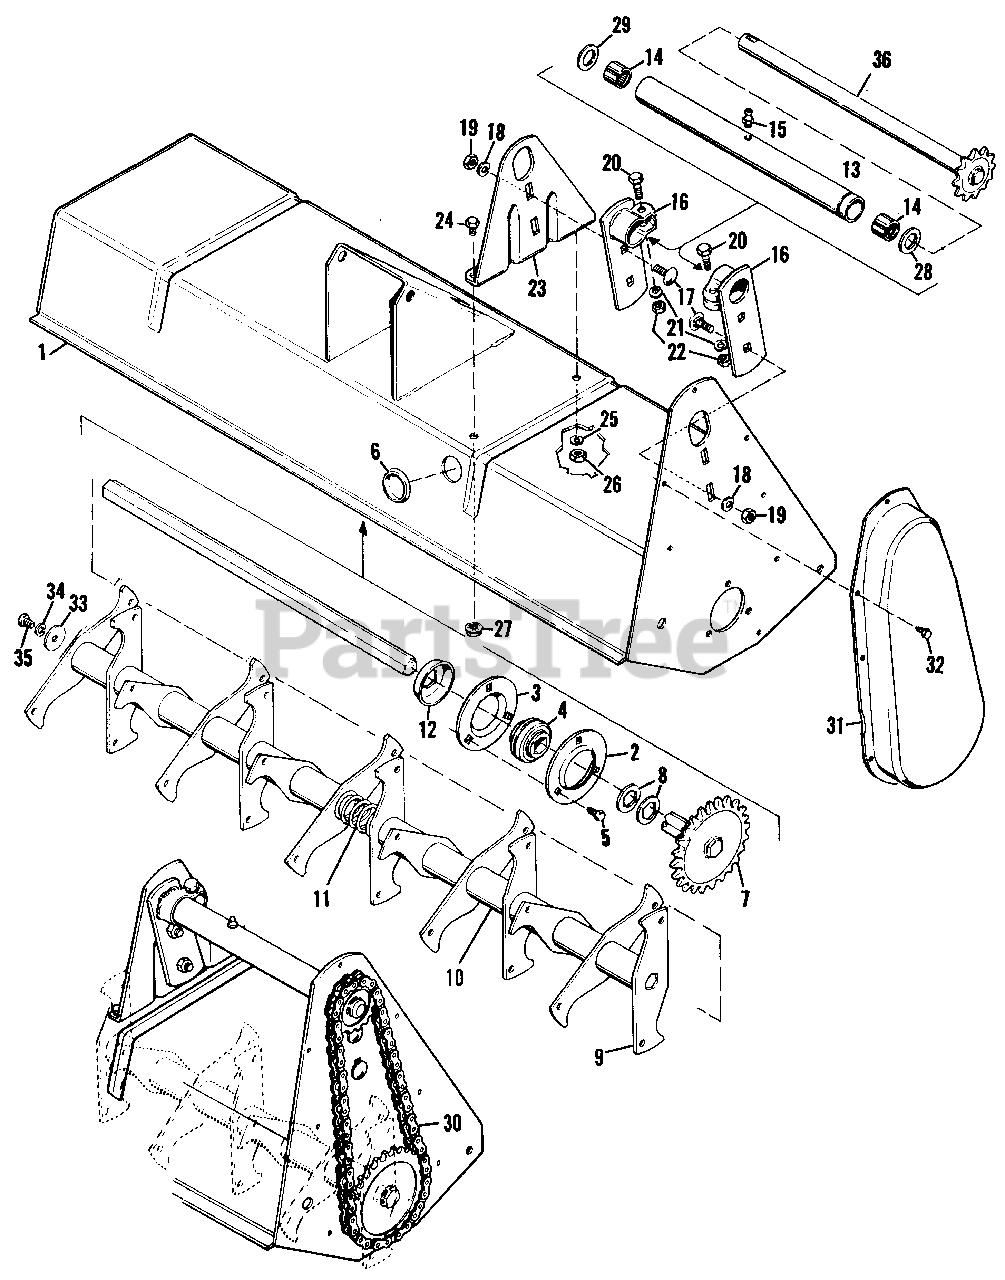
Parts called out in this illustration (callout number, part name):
1	Housing Assembly
2	Bearing Flange
3	Bearing Flange
5	Hex Hd. Swageform Screw, 5/16"-18 x 1/2" lg.
6	Plug Button
7	Tine Shaft Assembly
8	Washer (Hex)
12	Trash Guard
13	Bearing Housing
14	Needle Bearing
15	Grease Fitting
16	Clamp Support Assembly
17	Carriage Bolt, 7/16"-14 x 1" lg.
18	Lock Washer, 7/16"
19	Hex Jam Nut, 7/16"-14
20	Hex Capscrew, 5/16"-18 x 1-1/2" lg.
21	Lock Washer, 5/16"
22	Hex Nut, Full, 5/16"-18
23	Bearing Support
24	Hex Capscrew, 5/16"-18 x 5/18" lg.
25	Lock Washer, 5/16"
26	Hex Nut, Full, 5/16"-18
27	Special Nut, 5/16"-18
31	Chain Guard
32	Taptite Screw, 1/4"-20 x 3/8"
34	Lock Washer, 5/16"
35	Hex Capscrew, 5/16"-18 x 1/2" lg.
36	Drive Shaft Assembly
